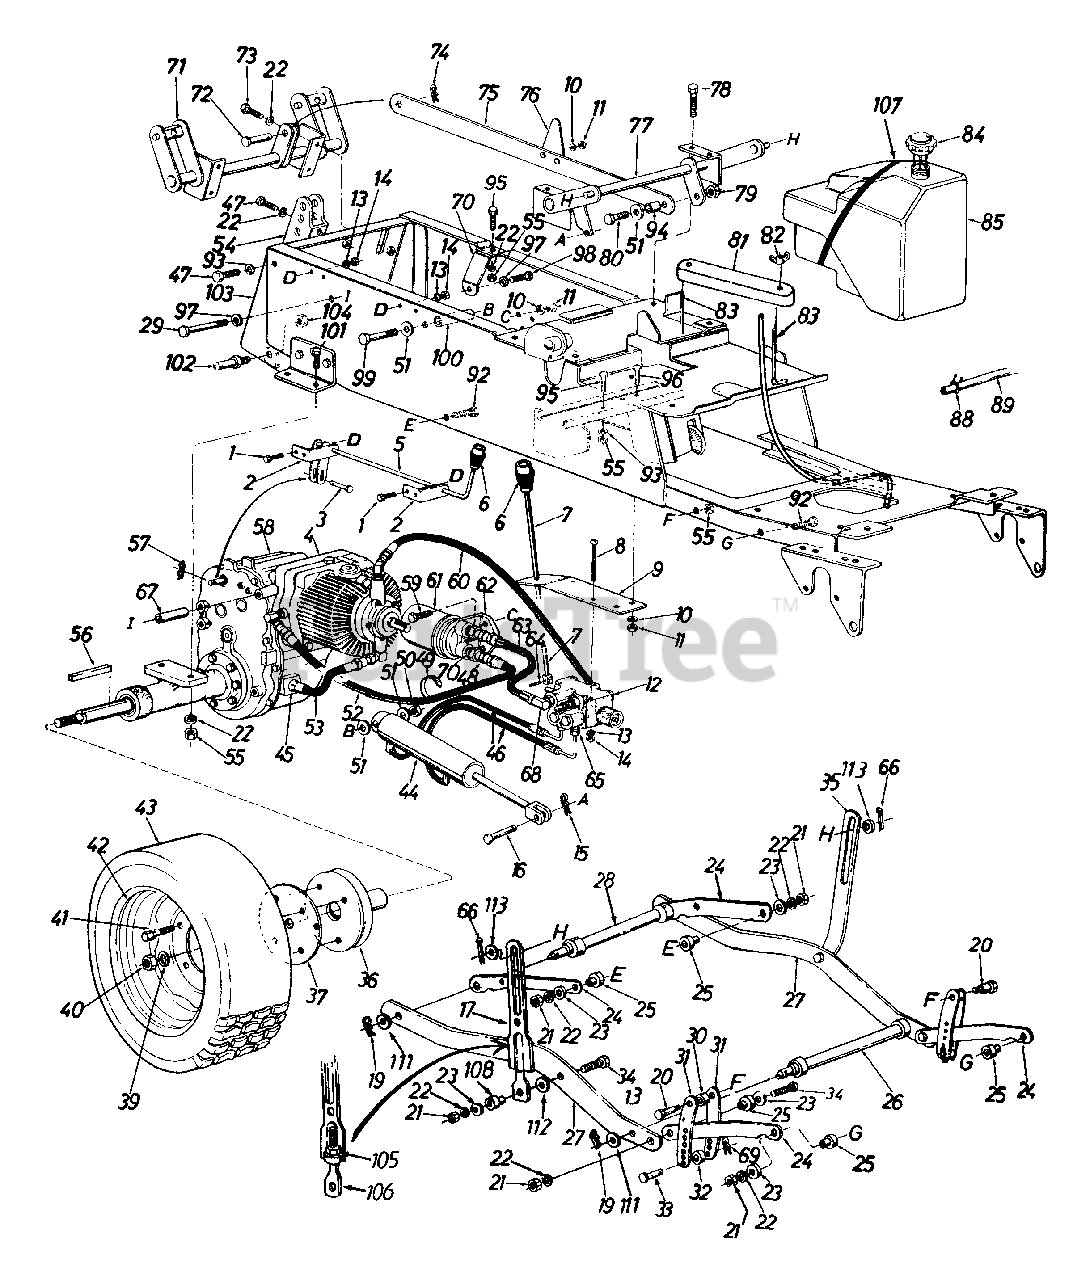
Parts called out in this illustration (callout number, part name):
1	Hex Bolt 1/4-20 x .75" Lg.
4	Hydrostatic Pump Comp.
5	Hi-Lo Control Handle Ass'y.
6	Shift Knob
7	Cylinder Control Handle Ass'y.
8	Truss Mach. Scr.1/4-20 x 3" Lg.
11	Hex Nut 5/16-18 Thd.
12	Valve Ass'y. Comp.
13	L-Wash. 1/4" I.D.
14	Hex Nut 1/4-20 Thd.
15	Hairpin Cotter 1/2" Dia.
16	Clevis Pin 1/2" Dia.
17	Adj. Deck Link
19	Hairpin Cotter
20	Shld. Bolt .498" Dia. x .66"
21	Hex Nut 3/8-24 Thd.
22	L-Wash. 3/8" I.D.- H.D.
23	Fl-Wash .38" I.D. x 1.00"
26	Cross Shaft Ass'y.- Front
29	Hex Bolt 1/2-13 x 2.75"
30	Collar .50" I.D. x 1.0"
33	Clevis Pin 3/8" Dia.
34	Hex Bolt 3/8-24 x 1.50" Lg.- Grade 5
39	L-Wash. 3/4" I.D.
40	Hex Ins. L-Nut 3/4-16 Thd.
41	Wheel Lug Bolt
44	Hydraulic Cylinder
45	7/8-14 UNF-2A Thd. 5/8 Tube Fltting
46	Valve to Cylinder Hose - 20"
47	Hex Bolt 3/8-16 x .75" Lg.- Grade 5
48	Bushing Reducer 1/2-14 NPTF to 3/8-18 NPTF
49	Cable Tie
50	Hex Jam Nut 1/2-20 Thd.
51	Fl-Wash .50" I.D. x 1.25
52	Fllter Return Hose 24" Lg.
53	Pump Tube Ass'y.
55	Hex Nut 3/8-16 Thd.
56	Sq. Key 1/4" x 1/4" x 2"
57	Hairpin Cotter 1/4" Dia.
58	Peerless Transaxle
59	Hex Bolt 5/16-18 x 1.25"
60	Pump to Valve Hose
61	Fram Fllter Ass'y. PH-16
62	Fllter Base
63	Valve to Fllter Hose - 8.38"
64	Spring Pin Spiral 1/8" Dia.
65	Flare Adapter
66	Cotter Pin 1/8" Dia. x 1.0"
67	Spacer
68	Adapter 9/16-18 to 9/16-18
69	Hairpin Cotter
70	Transmission Brace
73	Hex Scr. 3/8-16 x 1.00" Lg. Grade 5
74	Cotter Pin 1/8" Dia. x 1.25"
79	Hex Cent. L-Nut 1/2-20 Thd.
80	Hex Bolt 1/2-20 x 1 25" Lg.
81	Battery Cover
82	Wing Nut 1/4-20 Thd.
83	Battery Hold Down Rods
84	Gas Tank Cap
85	Gas Tank Ass'y.
88	Gas Line Clamp 1/2"
89	Gas Line 46" Lg.
92	Hex Bolt 3/8-24 x 1.5" Lg.
93	L-Wash. 3/8" I.D.
94	Push Bar Sleeve
95	Hex Bolt 3/8-16 x 1" Lg - Grade 5
96	Hex Bolt 5/16-18 x .75" Lg.
97	L-Wash 1/2" I.D.
98	Hex Bolt 1/2-13 x 1.25" Lg.
99	Hex Bolt 1/2-20 x 3-1/2" Lg.- Grade 5
100	Spacer for Cylinder
101	Hex Bolt 3/8-16 x 1.75" Lg.
102	Link Clevis Pin
105	Hex Nut 1/2-13 Thd
106	Eye Bolt
107	Tie Strap
108	Spacer 385" I.D.
111	Fl-Wash .63" I D. x .93" O.D
112	Fl-Wash .381" I.D. x .87" O.D.
113	Fl-Wash .5" I.D. x 1" O.D.
